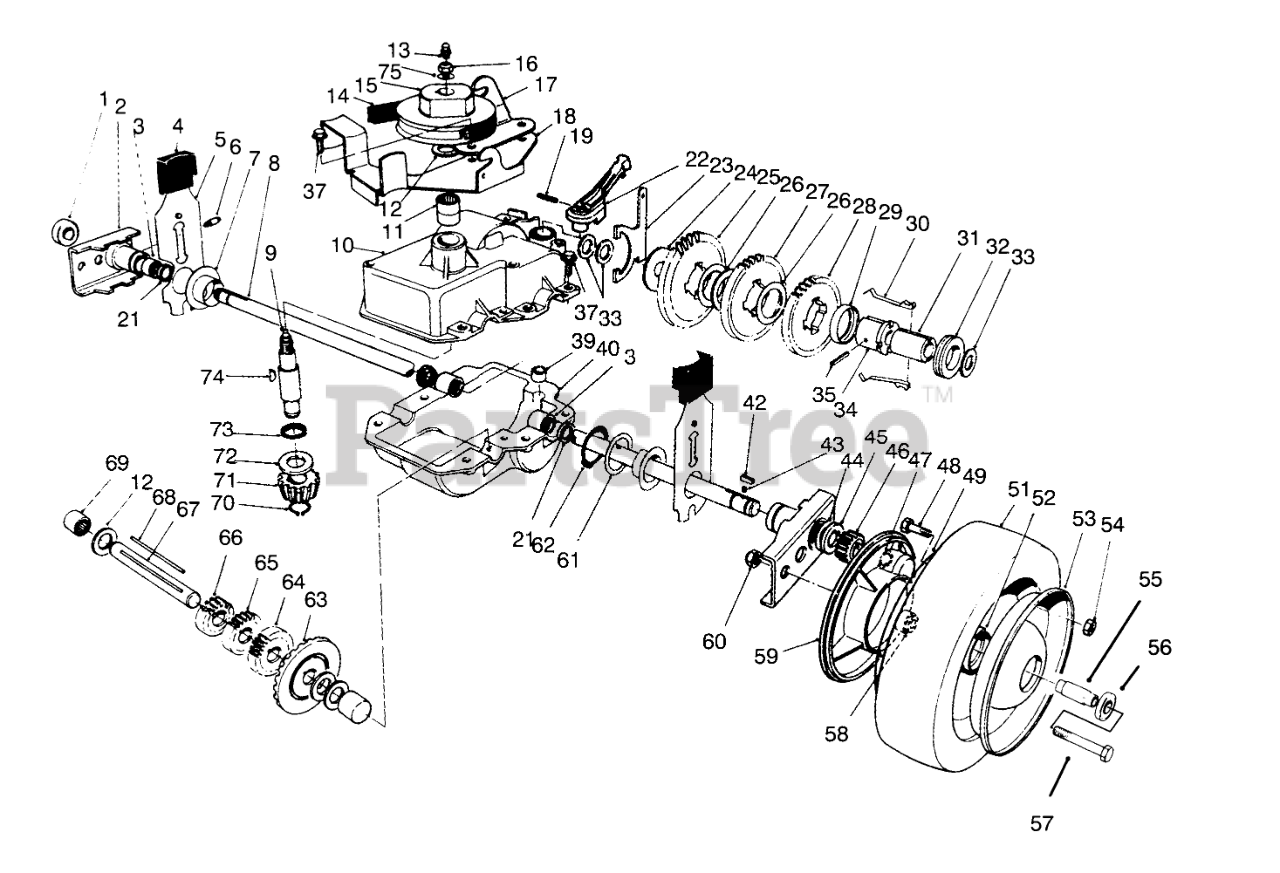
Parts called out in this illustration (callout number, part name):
1	BEARING-WHEEL
2	Pivot Arm Assembly (Incl Ref. #1,3,6,21)
3	BEARING-ROLLER
4	KNOB-ARM
5	REAR SPRING ARM ASM
7	CAP-END
8	SHAFT-OUTPUT
9	Shaft-Input (Incl Ref. #13)
10	Upper Case Assembly (Incl Ref. #11,73)
11	BEARING-NEEDLE
12	WASHER-THRUST
13	FITTING-GREASE, ZERK
14	V-BELT
15	PULLEY
16	NUT-HEX
17	Bracket-Traction Engage
18	Belt Guide Bracket
19	PIN-COIL
21	SEAL-OIL
22	LEVER-SHIFT
23	YOKE-SHIFT
24	WASHER
26	WASHER
27	GEAR-42T
28	GEAR-38T
29	RETAINER-KEY
30	KEY-SHIFT
31	SLEEVE
32	COLLAR-SHIFT
33	WASHER-PLAIN
34	SLEEVE-GEAR
35	PIN-GROOVE
37	SCREW-HWHTF
39	BUSHING-YOKE
40	CASE-GEAR, LOWER
43	SPRING-COMPRESSION
44	WASHER-THRUST, OUTER
45	WASHER-THRUST, OUTER
46	GEAR-PINION
47	RING-RETAINING
48	SCREW-HH
49	Wheel-Half
52	HUB-BEARING
53	Wheel-Half
54	NUT-LOCK, NI
55	SPACER-BEARING
56	BEARING-WHEEL
57	SCREW-HH
58	SPACER-COVER, WHEEL
59	COVER-WHEEL
60	NUT-LOCK, CONE
61	WASHER
62	RING-RETAINING
63	GEAR-BEVEL
64	GEAR-18T
65	GEAR-14T
66	GEAR-12T
67	SHAFT-INTERMEDIATE
69	BEARING-NEEDLE, CLOSED
70	RING-RETAINING
71	PINION-BEVEL
72	WASHER-THRUST
74	KEY-WOODRUFF
75	WASHER-FLAT
